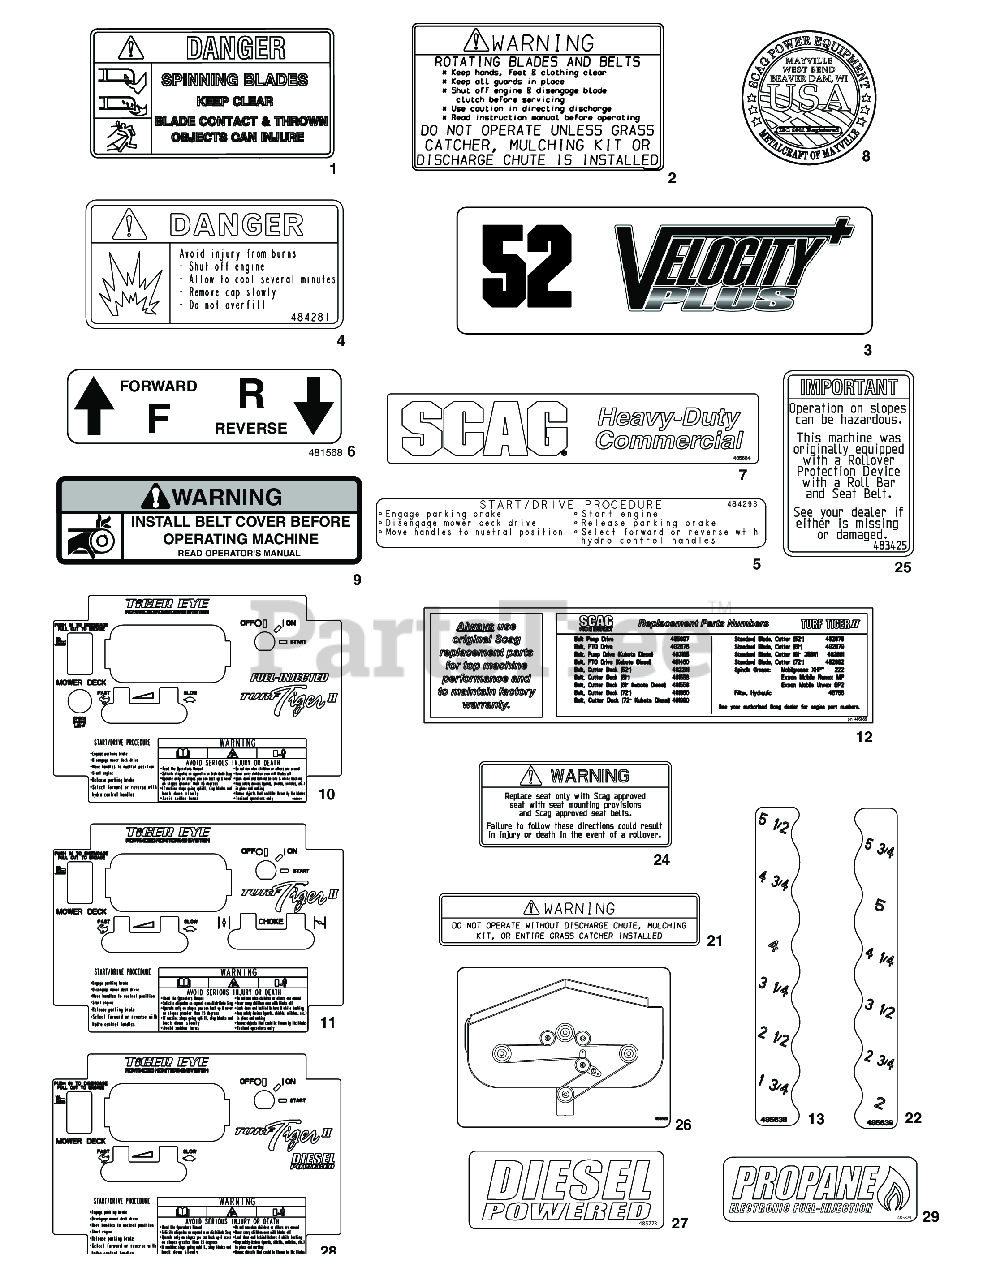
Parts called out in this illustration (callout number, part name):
1	Decal, Danger - Spinning Blades
2	Decal, Warning - Rotating Blades
3	Decal 52V 483201 Decal 61V
3	DECAL, VELOCITY PLUS - 61
3	Decal, 72" Velocity Plus
4	Decal, Fuel Tank - Gasoline Engines
4	Decal, Fuel Tank - Kubota Diesel
5	Decal, Start/Drive Procedure
6	Decal, Traction Control
7	Decal, Heavy-Duty Commercial
8	Decal, Metalcraft - USA
9	Decal, Warning - Belt Cover
10	Decal, Instrument Panel - Fuel Injected
11	Decal, Instrument Panel
12	Decal, STTII Replacement Parts
13	Decal, Cutting Height - LH
22	Decal, Cutting Height - RH
24	Decal, Seat Replacement
25	Decal, ROPS
26	Decal, Belt Routing
27	Decal, Diesel Powered - Kubota Diesel
28	Decal, Instrument Panel - Kubota Diesel
29	Decal, Propane - Kohler LP-EFI
